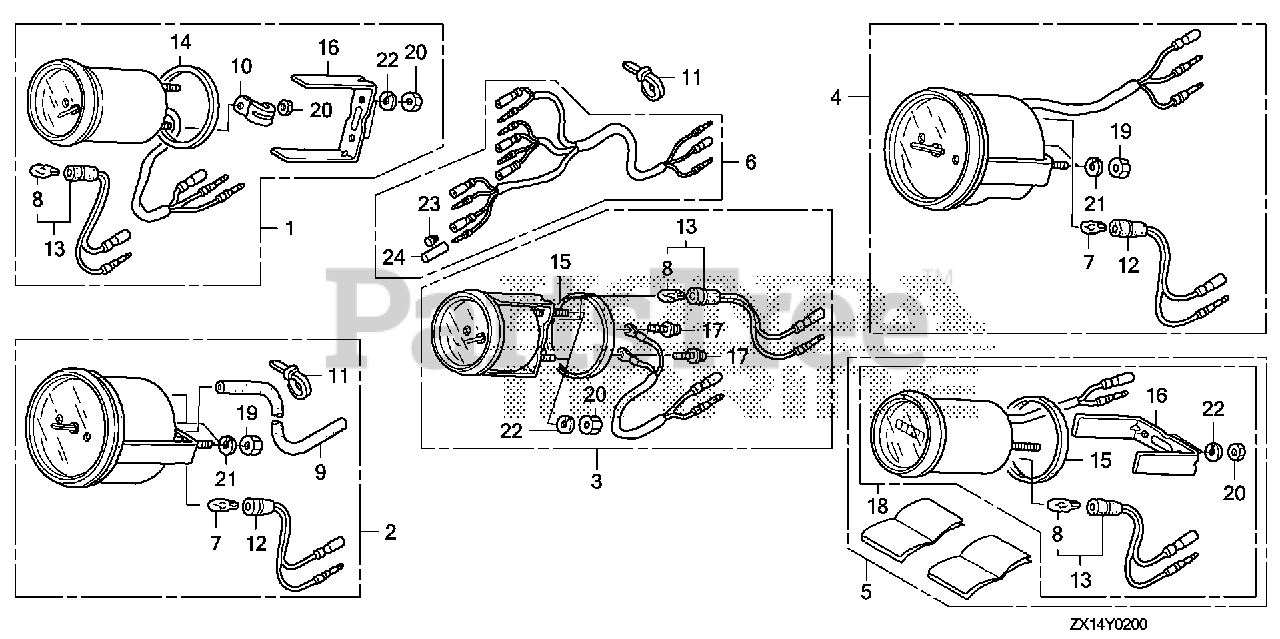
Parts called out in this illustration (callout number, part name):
1	METER KIT, TRIM (WHITE)
1	METER KIT, TRIM (B) (BLACK)
2	SPEEDOMETER KIT (WHITE)
2	SPEEDOMETER KIT *NHA85* (B) (BLACK)
3	METER KIT, VOLT (WHITE)
3	METER KIT, VOLT *NHA85* (B) (BLACK)
4	METER KIT, TACHO
4	METER KIT, TACHO (B)
5	METER KIT, HOUR (WHITE) (NA USE ALT:39700-ZW5-000ZA)
5	METER KIT, HOUR (B) (NA USE ALT:39700-ZW5-000ZA)
6	HARNESS ASSY., METER (B)
7	BULB, WEDGE BASE (T10) (12V 1.7W) (STANLEY)
8	BULB, WEDGE BASE (12V1.7W) (TOSHIBA)
9	TUBE, SPEED METER (4X7X8000)
10	CLAMP
11	BAND, SELF-LOCK
12	SOCKET
13	SOCKET
14	GASKET (TO 1015209) (FROM 1015210)
15	GASKET
16	BRACKET (TO 1015209) (FROM 1015210)
17	SCREW-WASHER (3X22)
18	METER ASSY., HOUR
18	METER ASSY., HOUR (B)
19	NUT, HEX. (5MM)
20	NUT, HEX. (4MM)
21	WASHER, SPRING (5MM)
22	WASHER, SPRING (4MM)
23	PLUG, CONNECTOR (INNER) (TROLLING CONTROL)
24	PLUG, CONNECTOR (OUTER) (ENGINE NO.)
